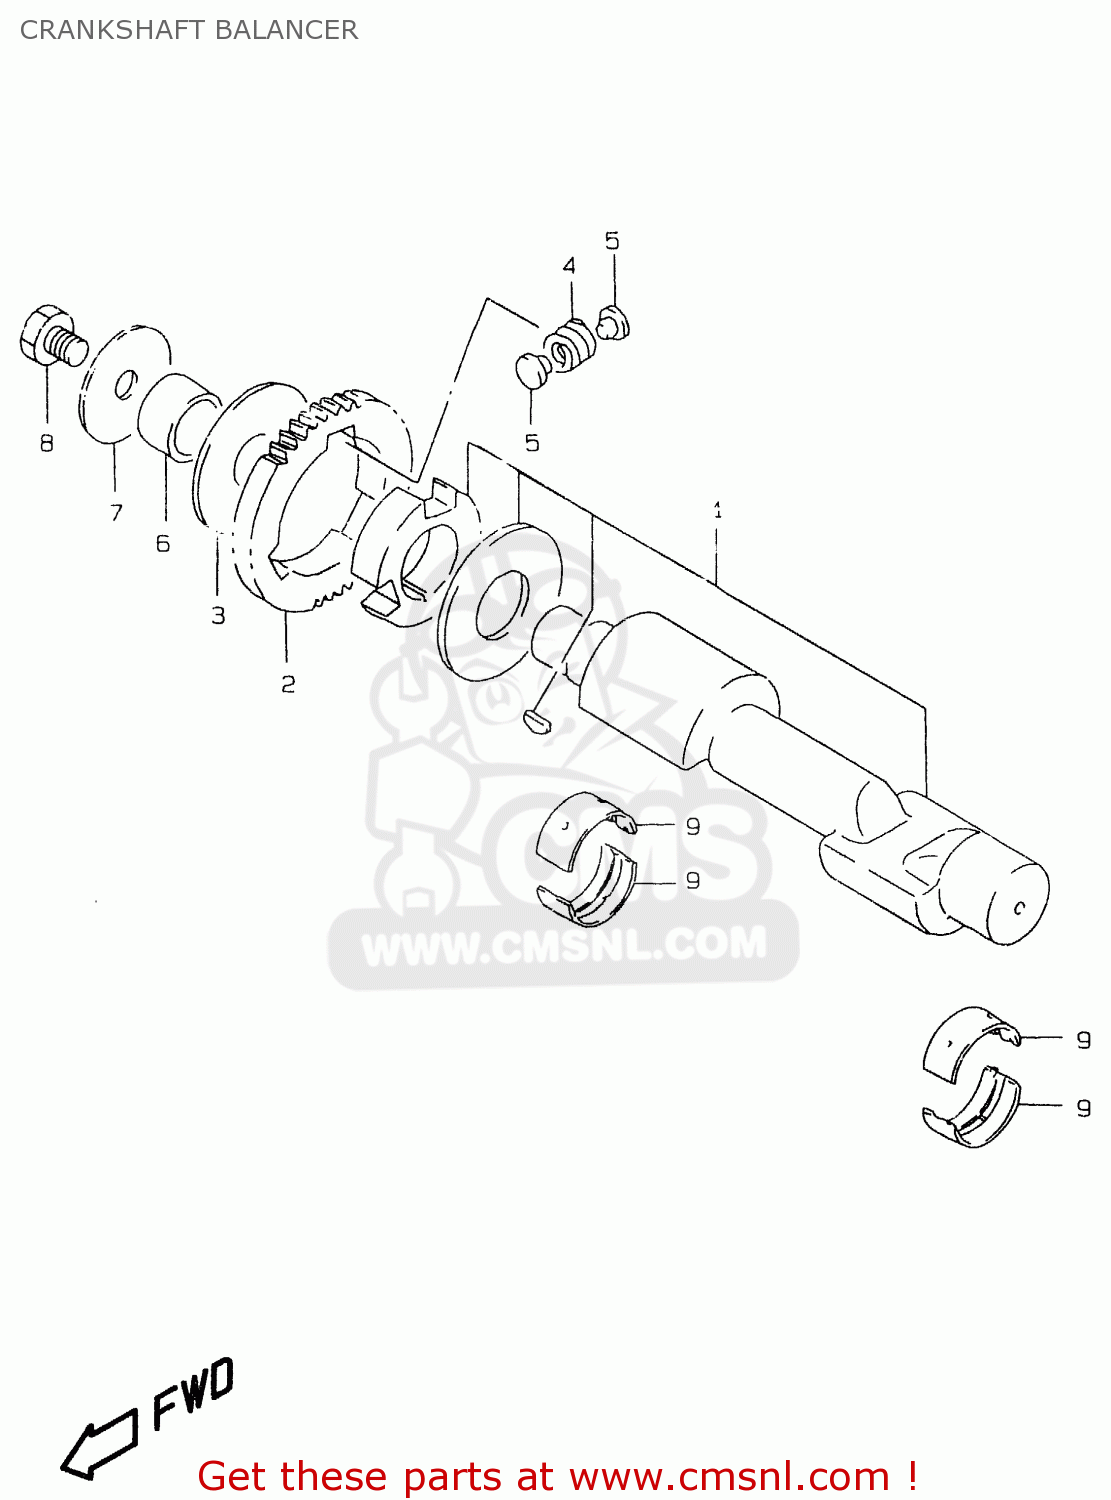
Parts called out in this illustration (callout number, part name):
1	BALANCER,CRANK
2	GEAR,CRANK BALANCER DRIVE
3	WASHER(24X70X3)
4	SPRING
5	PIN
6	SPACER(24X30.5X12.5)
7	WASHER(12X50X3)
8	BOLT
9	BEARING,CRANKSHAFT(GREEN)
